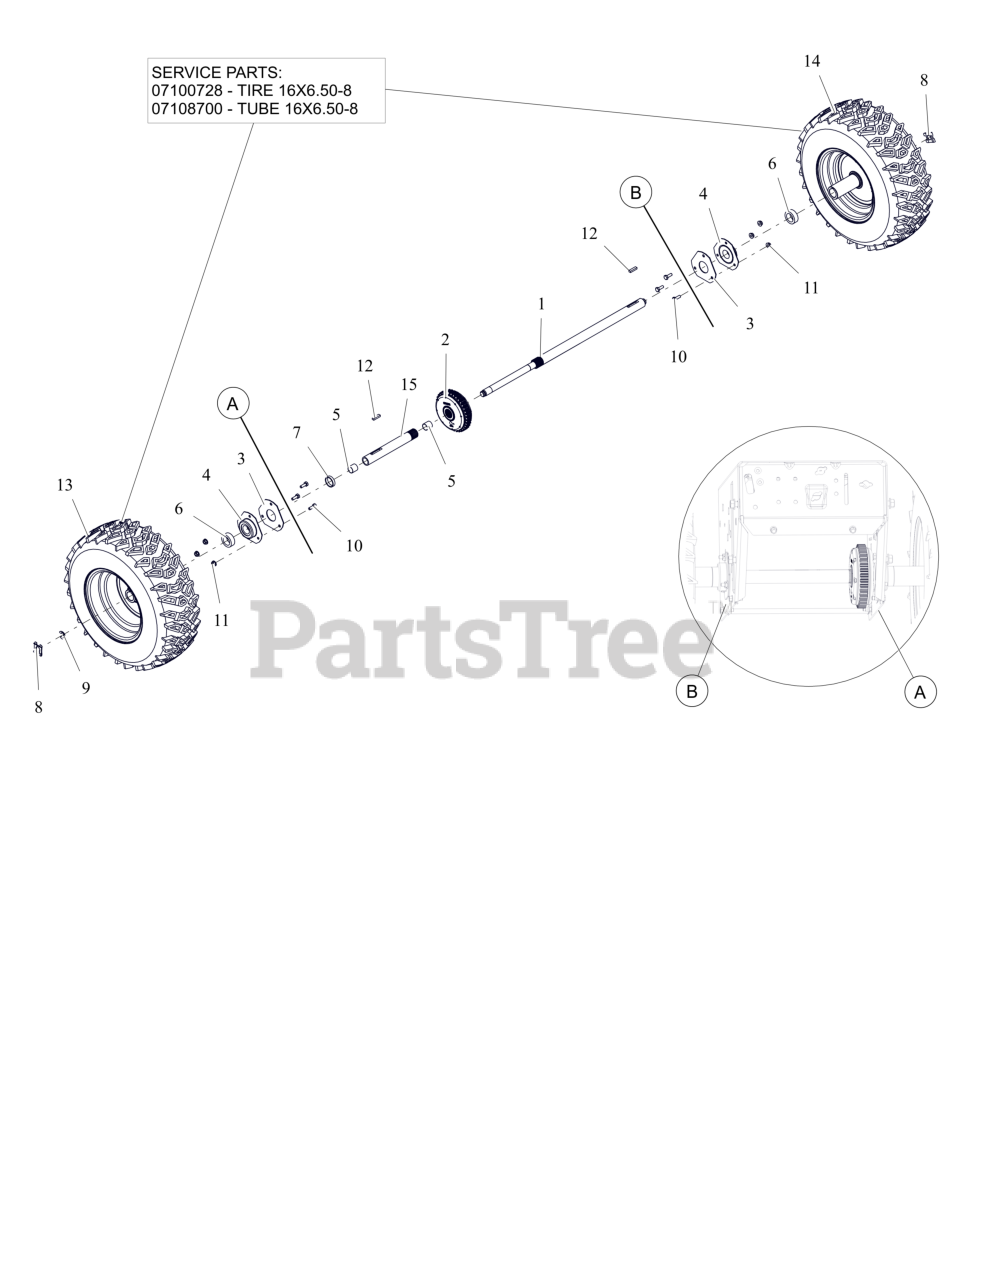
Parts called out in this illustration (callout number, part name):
1	AXLE, LONG-PRO AUTO DIFF
2	DIFFERENTIAL, AUTOMATIC
3	PLATE, BEARING SPACER
4	BRG-FLG 1.003/1.000 3 BOLT
5	BSHG-SLV .706X.764X.75 BRZ
6	SPACER, PRO AXLE BEARING
7	BSHG, SLV 1.062X1.228X.268
8	CLIP, SNAP .625 DIA
9	RG-RTNG-EXT .625X.042
10	BLT, HEX .25-20X.75 G5 ZCC
11	NUT-LK-CTR-FLG .25-20 ZC120
12	KEY-RECT .25X.188X1.00
13	TIRE/WHEEL RH 16X6.5-8 DIFF T2
13	SNOW TIRE, 16/6.50-8 K478 DIRECTIONAL
13	TIRE TUBE 16X6.50/7.50-8 4 PLY TR13 STRIGHT VALVE
14	TIRE/WHEEL LH 16X6.5-8 DIFF T2
14	SNOW TIRE, 16/6.50-8 K478 DIRECTIONAL
14	TIRE TUBE 16X6.50/7.50-8 4 PLY TR13 STRIGHT VALVE
15	AXLE, SHORT-AUTO W/BUSHINGS
